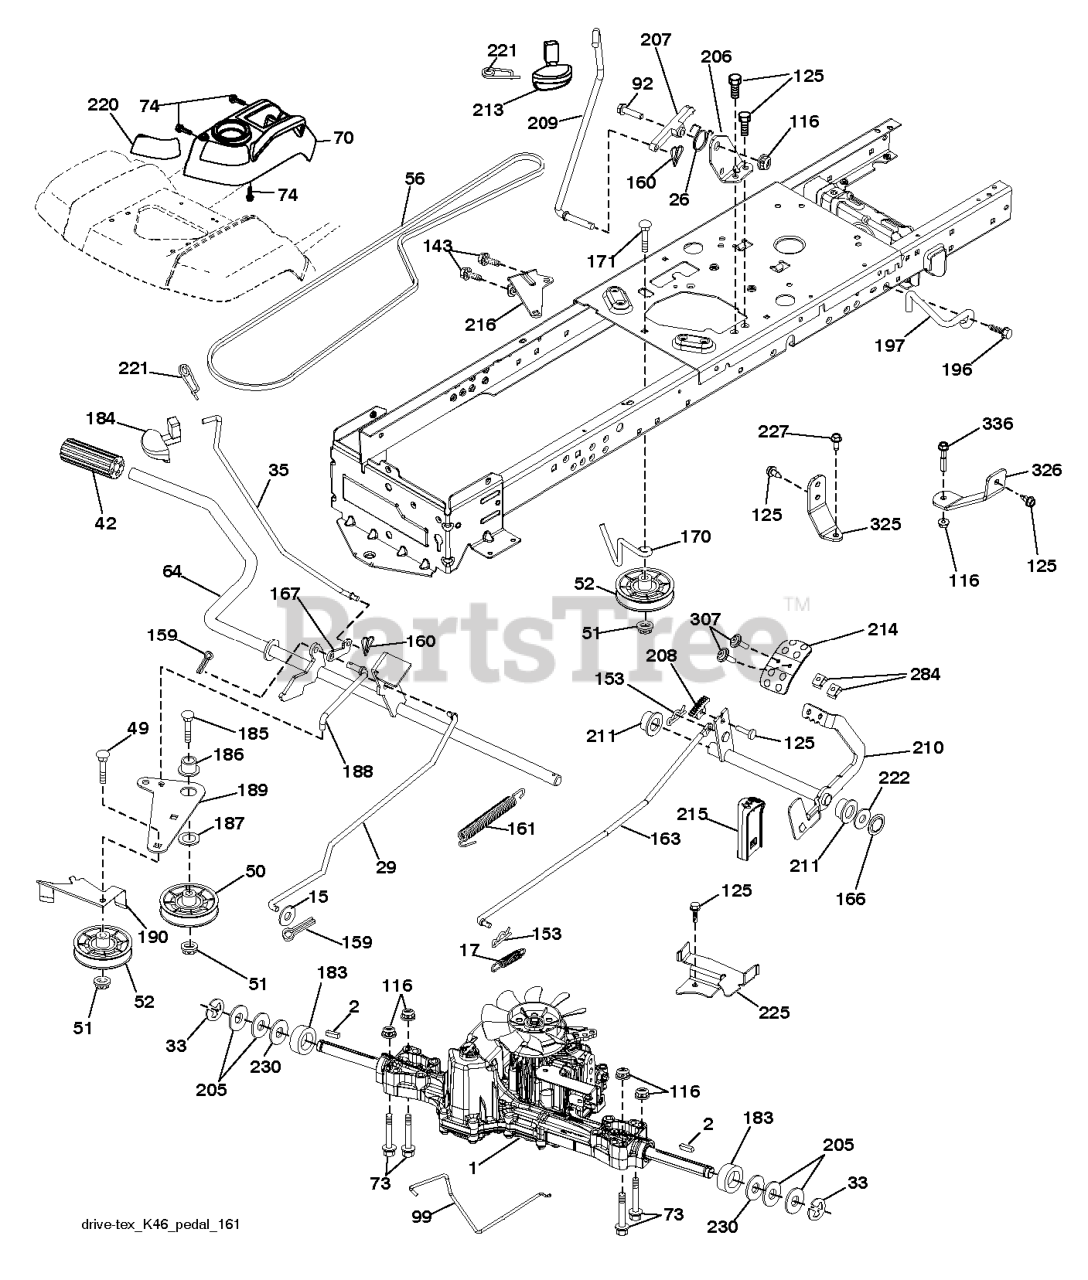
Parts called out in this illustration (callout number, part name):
2	SQUARE KEY
15	WASHER
17	SPRING.BRAKE.K46.GREEN
26	SPRING.RETURN.CRUISE
29	ROD.BRAKE.K46
35	ROD .BRAKE. PARKING. GT. HUSQ.
42	PEDAL COVER T
50	IDLER.FLAT.910.OFFSET
51	NUT LOCK FLG 3/8-16 UNC
52	IDLER.V-GROOVE.910.OFFSET
56	V-BELT.MOWER.92.40.42/K46
64	SHAFT.ASM.PEDAL.BRK.CNTR
70	CONSOLE.ASM.RH.GT.FC.HUSQ
73	BOLT
74	SCREW.HI-LO.CONSOLE
92	BOLT
99	ROD.SPRING.BYPASS.K46.LT.Z
116	NUT LOCK HEX FLANGE 5/16-18
125	SCREW
143	Screw 5/16-18 x 1/2 Hex, Self Tapping 5/16-18 x 1/2
153	RETAINER M
159	COTTER PIN
160	RETAINER CLIP
161	SPRING, RETURN LT
163	ROD.CONTROL.K57R.K46
166	NUT.PUSH.625
167	LATCH.BRAKE.SPRING
170	KEEPER.V-IDLER.CENTER.
171	BOLT
183	SPACER AXLE
184	RB HANDLE.PARKG.BRK.HUS/PRED
186	SPACER.RETAINER
187	WASHER 12/32X2X10GA
188	RP.LINK.CLUTCH.GROUND.DRIVE
189	BELLCRANK.GROUND.DRIVE.TEX.
190	KEEPER.BELLCRANK.DRIVE
196	SCREW 3/8-16X1
197	CLUTCH.ANTIROTATION.WIREFORM.
206	BRACKET.MOUNT.CRUISE.LATCH
207	LATCH.CONTROL.CRUISE
208	GEAR.SECTOR.CONTROL.CR
209	ROD.CONTROL.CRUISE.GT.
210	ROCKER.ASM.PEDAL.CONTR
211	BEARING.NYLON
213	KNOB.CONTROL.CRUSIE.HU
214	PEDAL.FORWARD.HUSQVARNA.DEALER
215	PEDAL.REVERSE.TEX.GT.4
216	BRACKET.PULLEY.IDLER.W/TEX
220	REFLECTOR.RH.TEX GT
221	RETAINER.SPRING.CLIP.H
222	WASHER 21/32 X 1-1/4 X 10 GA.
225	KEEPER.BELT.TRANSAXLE.K46
227	SCREW.THDROL.5/16-18X3/4.TTY
230	WASHER.HARDENED
284	NUT.U-CHNL.1/4-20.550DP.350PNL
307	SCREW.MACHINE.CR.1/4-20
325	BRACKET.TRQ.STP.46.20".TIRE.LH
326	BRCKT.PNT.TRQ.STP.46.20TIRE.RH
336	BOLT.5/16-18X1-3/4.FLANGED.HEX
